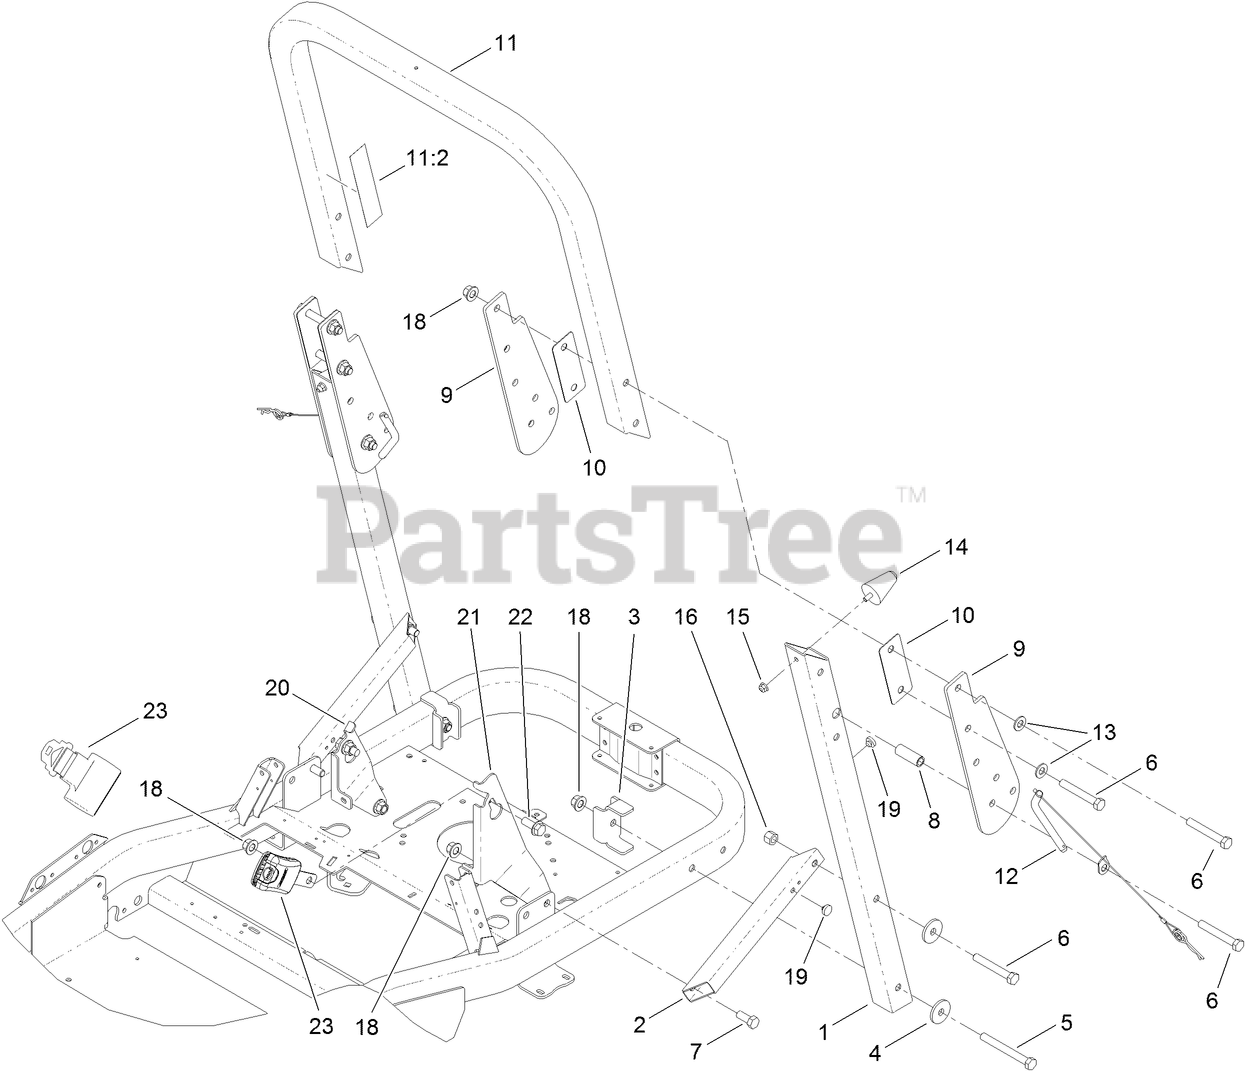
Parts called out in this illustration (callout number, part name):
1	TUBE-ROPS, LOWER
2	TUBE-SUPPORT, ROPS
3	BRACKET-REINFORCING
4	WASHER-THRUST
5	SCREW-HH
6	SCREW-HH
7	SCREW-HH
8	SPACER
9	BRACKET-PIVOT, ROPS
10	SPACER-ROPS
11	UPPER ROPS ASM
11:2	DECAL-WARNING
12	PIN-ROPS W/ LANYARD
13	WASHER-FLAT
14	BUMPER-RUBBER
15	NUT-HF, NI
16	NUT-HEX
18	NUT-LOCK
19	BUMPER
20	BRACKET-BELT, SEAT
21	BRACKET-BELT, SEAT
22	SCREW-HHF
23	SEAT BELT KIT
